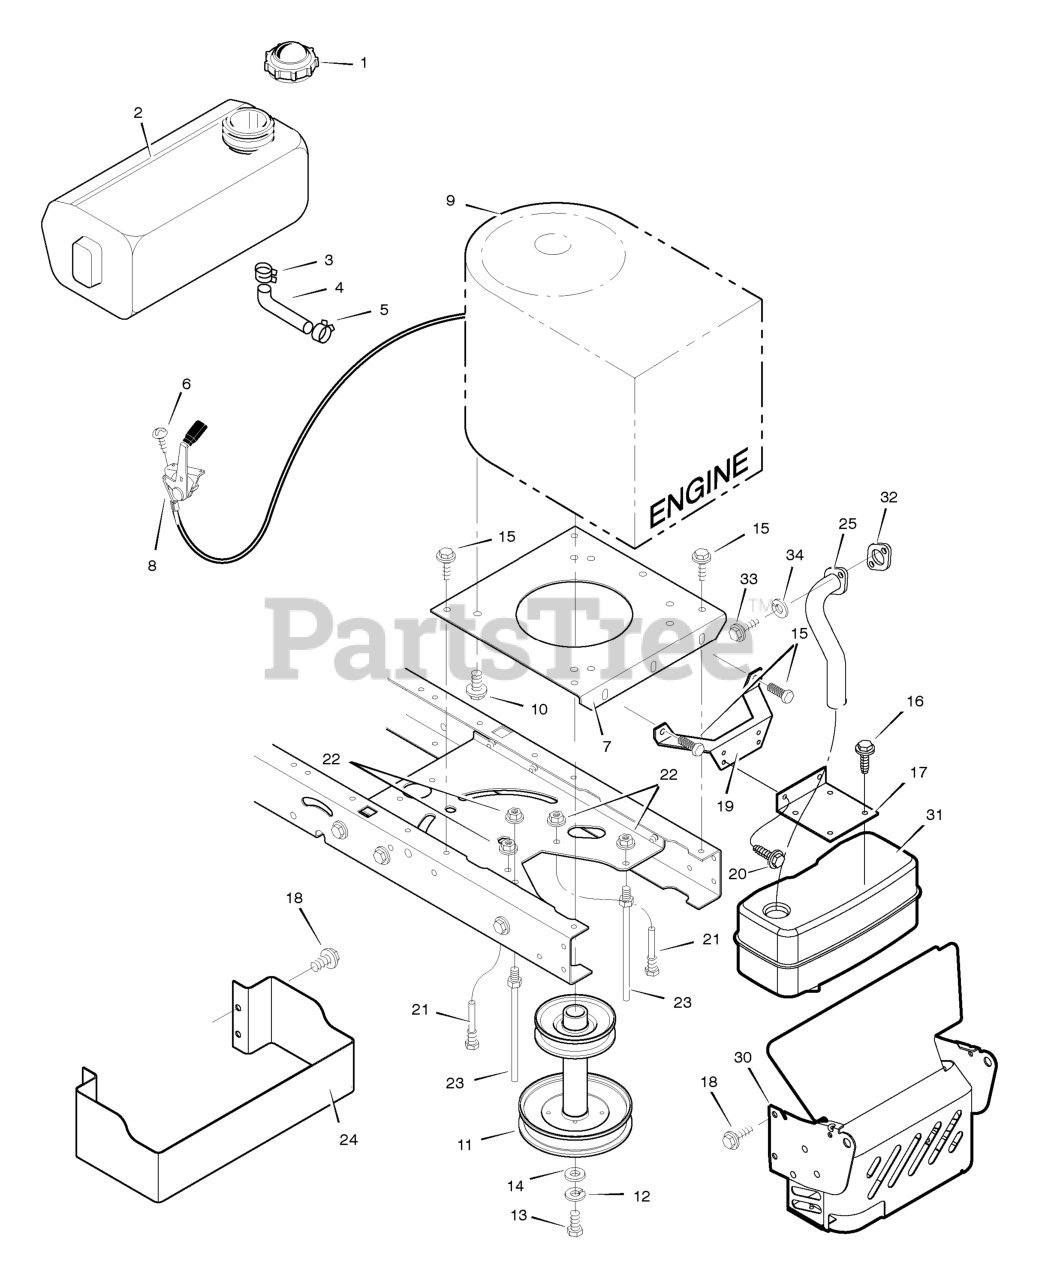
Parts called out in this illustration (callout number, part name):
1	Fuel Cap
2	Fuel Tank
3	Hose Clamp
4	Fuel Line (Must cut to length)
5	Hose Clamp
7	Plate, Engine
8	Throttle Control
9	Engine, Briggs & Stratton *
10	Bolt, Engine Mount
11	STACK PULLEY ASSEMBLY
12	Lockwasher
13	Bolt, Hex
17	Bracket, Muffler
19	Bracket, Muffler Mount
21	Guide, Belt
22	Nut, Flange
23	Guide, Belt
24	GUARD, Heat Shield
25	Exhaust Tube, Single
30	Shield, Heat
31	Muffler
32	GASKET, Exhaust
34	Washer
